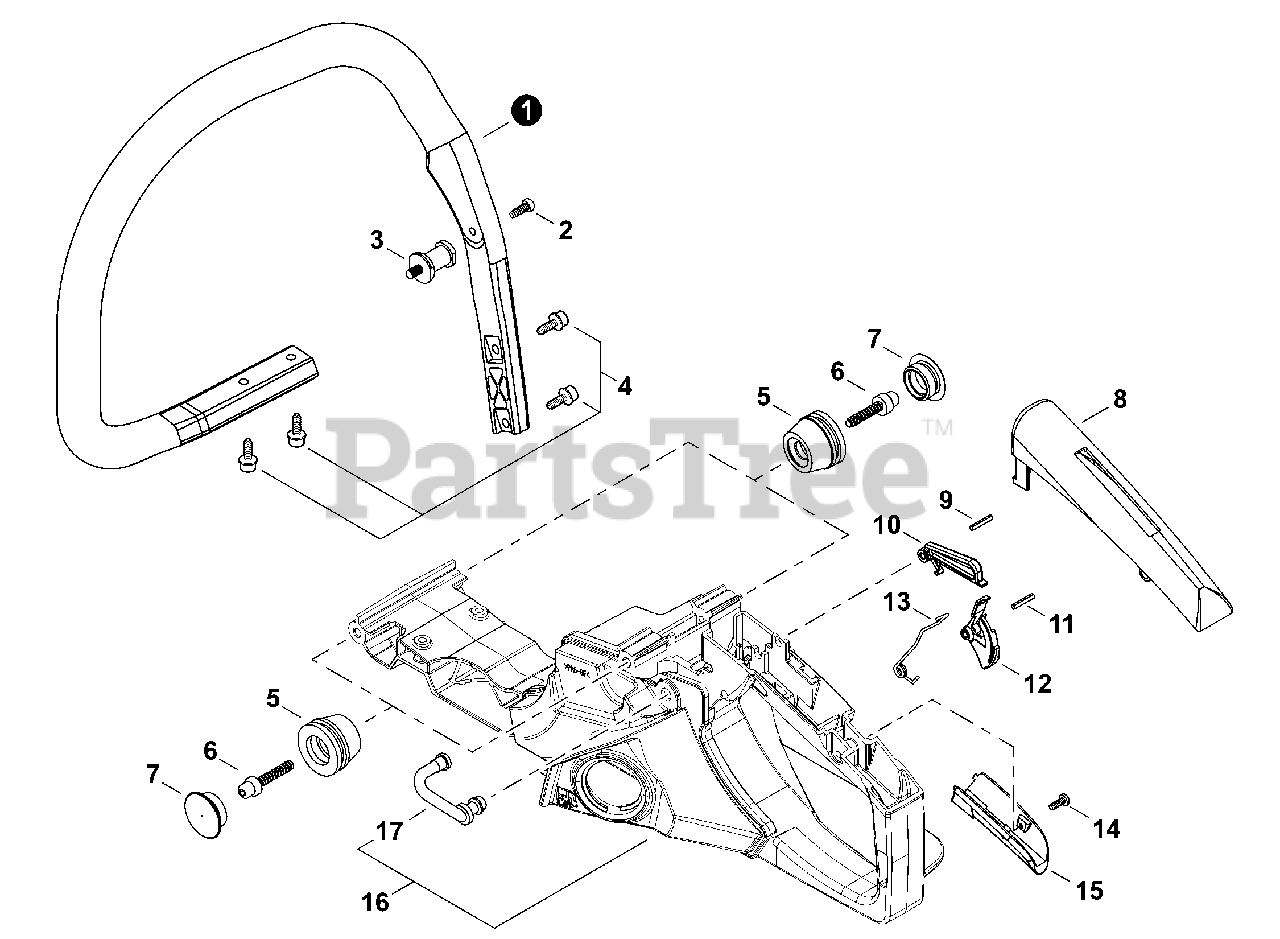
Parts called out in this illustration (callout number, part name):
1	HANDLE, FRONT
2	BOLT M4×14
3	CUSHION 5
4	BOLT 5×20
5	CUSHION
7	CAP, CUSHION
8	COVER, HANDLE
9	PIN, SPRING Ø4×22 MM
10	LOCKOUT, THROTTLE
11	PIN, SPRING Ø4×25 MM
12	TRIGGER, THROTTLE
13	SPRING, THROTTLE RETURN
14	SCREW 4×25
15	GRIP, HANDLE
16	HANDLE ASSY, REAR
17	PIPE, FUEL VENT
